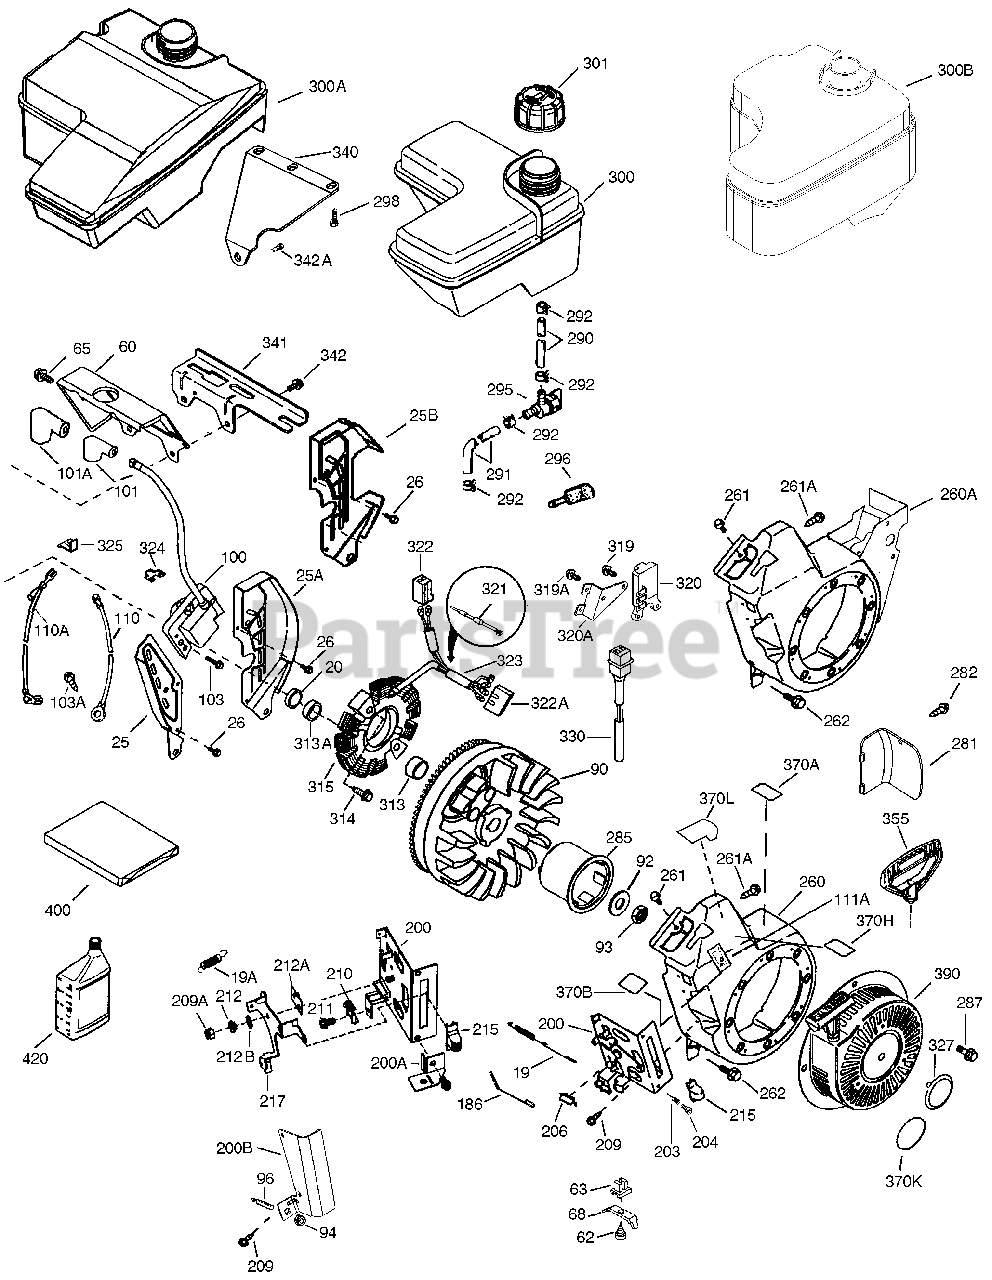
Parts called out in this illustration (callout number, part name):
19	Governor Spring
20	Oil Seal
25	Air Baffle (Left)
25A	Air Baffle (Right)
60	Blower Housing Extension
65	Screw, 10-24 x 9/16"
90	Flywheel
92	Belleville Washer
93	Flywheel Nut
94	Lock Nut, 10-32
96	RPM Adjusting Bolt
100	Solid State Ignition
101	Spark Plug Cover
103	Screw, Torx T-15, 10-24 x 15/16"
110	Ground Wire
110A	Ground Wire - Black, 4.13''
111B	Rocker On/Off/LOS Switch
124	Screw, 1/4-20 x 5/8"
200	Control Bracket
229	Nut, 1/4-20
229	Nut & Lock Washer
260	Blower Housing
285	Starter Cup
287	Rivet (Can be purchased locally)
287	Screw, 8-32 x 21/64"
290	Fuel Line
292	Fuel Line Clamp
298	Screw, 1/4-15 x 3/4"
300A	Fuel Tank (Incl. 292 & 301) (4 Quart)
301	Fuel Cap (Black)
325	Wire Clip
327	Starter Plug
338	Screw, 10-32 x 1/2"
340	Fuel Tank Bracket
341	Fuel Tank Bracket
342	Screw, 1/4-20 x 31/64"
342	Screw, 1/4-20 x 7/8"
365	Screw, 8-32 X 27/64``
370L	Oil Sensor Decal
390	Rewind Starter NOTE: This engine cou ld have been built with 590748 starte r.
400	* Gasket Set (Incl. items marked PK in notes) Incl. (1) each of 26756,27272A , 29673, 35626, 36581, 36624,36719
900	Replacement engine - None
900	Replacement S/B 754320, order from 71 -999
999	Summer Maintenance Kit (incl. Oil, Sp ark Plug, Air Cleaner, & Ultra Fresh)
